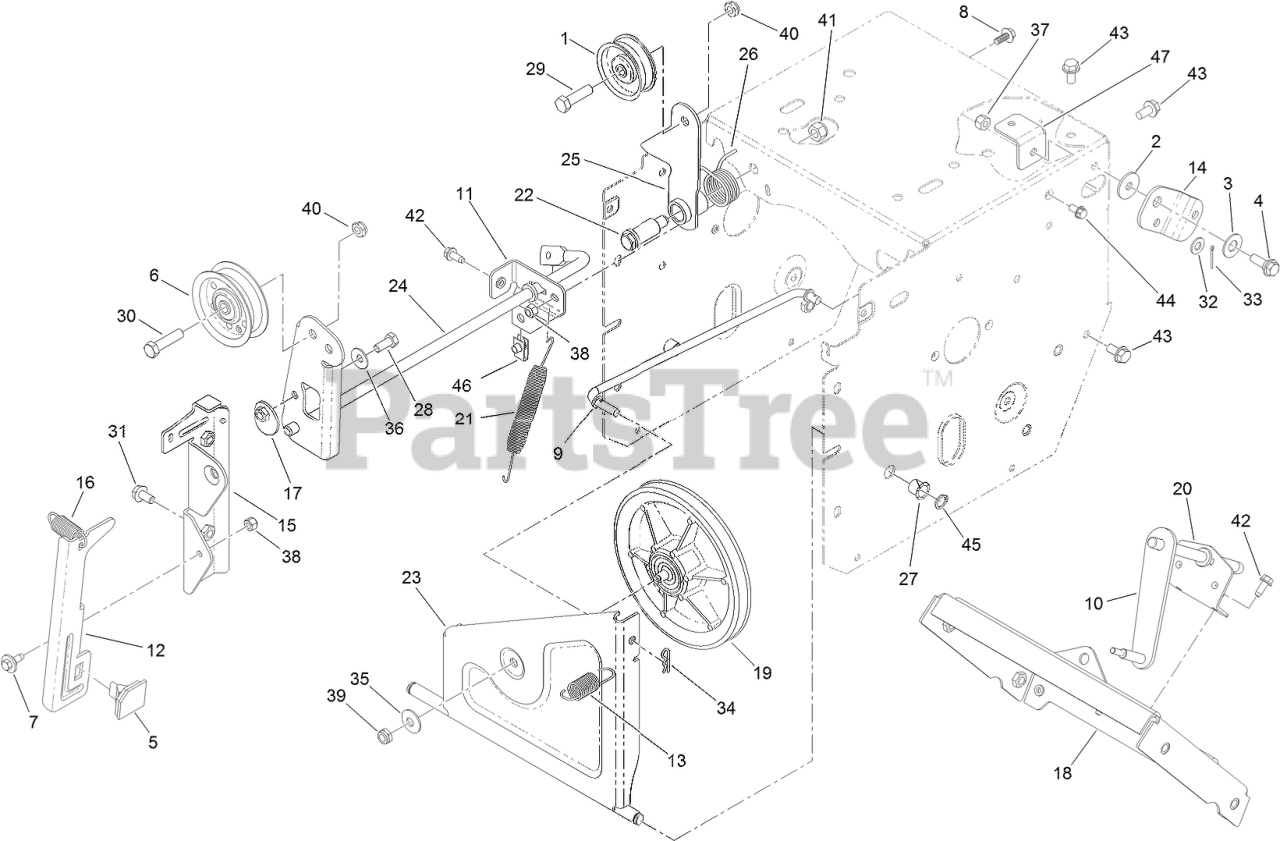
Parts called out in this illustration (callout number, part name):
1	PULLEY-IDLER
2	WASHER-PIVOT
3	WASHER
4	SCREW-SHOULDER
5	PAD-BRAKE
6	PULLEY-IDLER
7	SCREW-SHOULDER
8	SCREW-HHF
9	LINK-CONTROL, SPEED
10	LEVER-CONTROL, TRACTION
11	BRACKET-CLUTCH, IMPELLER
12	ARM-BRAKE
13	SPRING-EXTENSION
14	BELLCRANK-DRIVE
15	BRACKET-IDLER, IMPELLER
16	SPRING-EXTENSION
18	SHIFT PLATE ASM
19	PULLEY-TRACTION
20	BRACKET-ROD, SHIFT
21	SPRING-EXTENSION
22	BOLT-SHOULDER
23	BRACKET-WHEEL, FRICTION
24	IMPELLER CLUTCH ASM
25	ARM-IDLER, TRACTION
26	SPRING-TORSION
27	BUSHING-NYLINER
28	SCREW-HH
29	SCREW-HH
30	SCREW-HH
31	SCREW-HHF
32	WASHER-PLAIN
33	PIN-COTTER
34	PIN-COTTER
35	WASHER-BELLEVILLE
36	WASHER-BELLEVILLE
37	NUT-LOCK, NI
38	NUT-LOCK, NI
39	NUT-HEX
40	NUT-LOCK, NI
41	NUT-LOCK, NI
42	SCREW-HWH
43	SCREW-HWHTF
44	SCREW-HWH
45	RING-RETAINING
47	BRACKET-FRAME, LH
